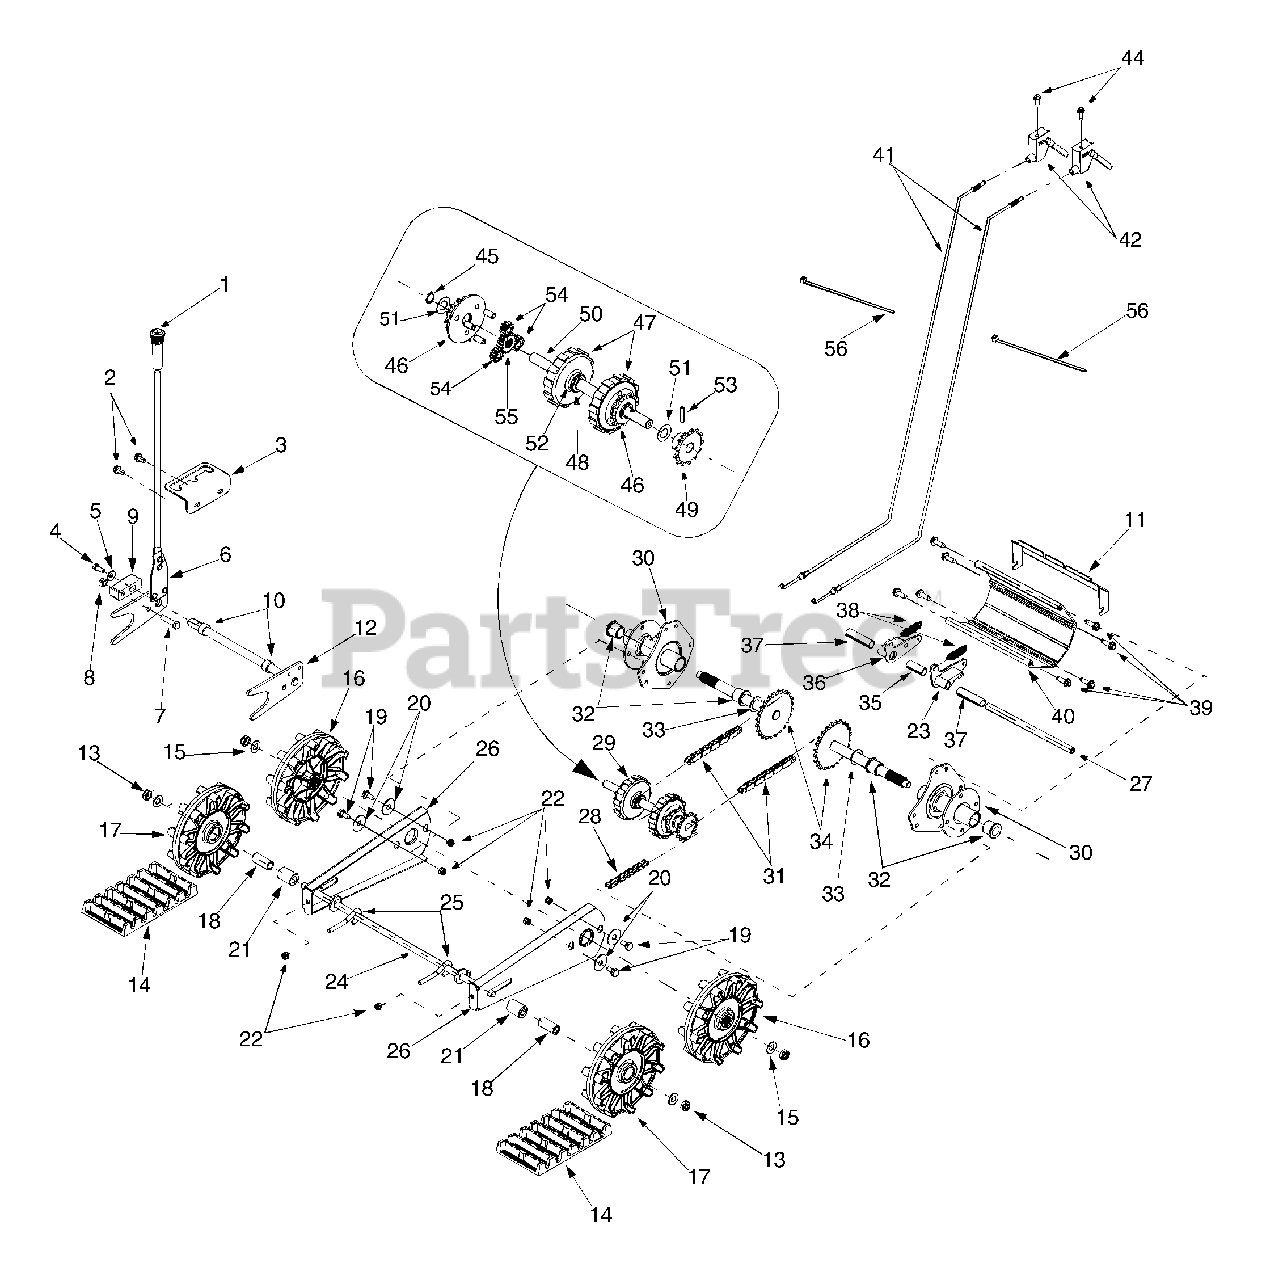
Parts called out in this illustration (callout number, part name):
2	Tap Screw, 5/16-12 x.750
4	Hex Cap Screw, 5/16-24 x.75
5	Bell Washer,.34 ID x.872 OD
7	Hex Cap Screw, 3/8-24 x 1.5
8	Hex Nut, 3/8-24
9	Lift Shaft Drive
10	Spacer,.628 ID x.875 OD x.5
13	Jam Nut, 1/2-20
14	Snow Track
15	Flat Washer,.5 x 1 x.06
16	Track Drive Wheel
17	Track Idler Wheel
18	Spacer,.51 ID x.75 OD x 1.67
19	Screw,.435 x.178-5/16 x.56
20	Flat Washer,.442 x 1.38 x.06
21	Spacer,.51 ID x 1 OD x 1.34
22	Flange Lock Nut, 5/16-18
23	LH Dogg Assembly
25	Eye Bolt, 5/16-18 x 3
27	Actuator Shaft
29	Track/Steering Shaft Ass'y
32	Flange Bearing
33	Flat Washer,.793 x 1.24 x.06
34	Axle Assembly
35	Spacer,.514 x.630 x 1.59
36	RH Dogg Assembly
37	Spacer,.514 x.630 x 2.44
38	Extension Spring
39	Tap Screw, 5/16-18 x 1
40	Track Housing
41	Steering Cable
42	Steering Trigger
44	Screw, #10-24 x 1.375
45	Retaining Ring
46	Carrier Assembly
48	Retaining Ring
49	13-Tooth Sprocket
50	Track Steering Drive Shaft
51	Flat Washer,.58 x 1.06 x.02
52	Flat Washer, 5/8 x 1 x.03
53	Spiral Pin, 3/16 x 1
54	12-Tooth Gear
55	18-Tooth Gear
56	Cable Tie
